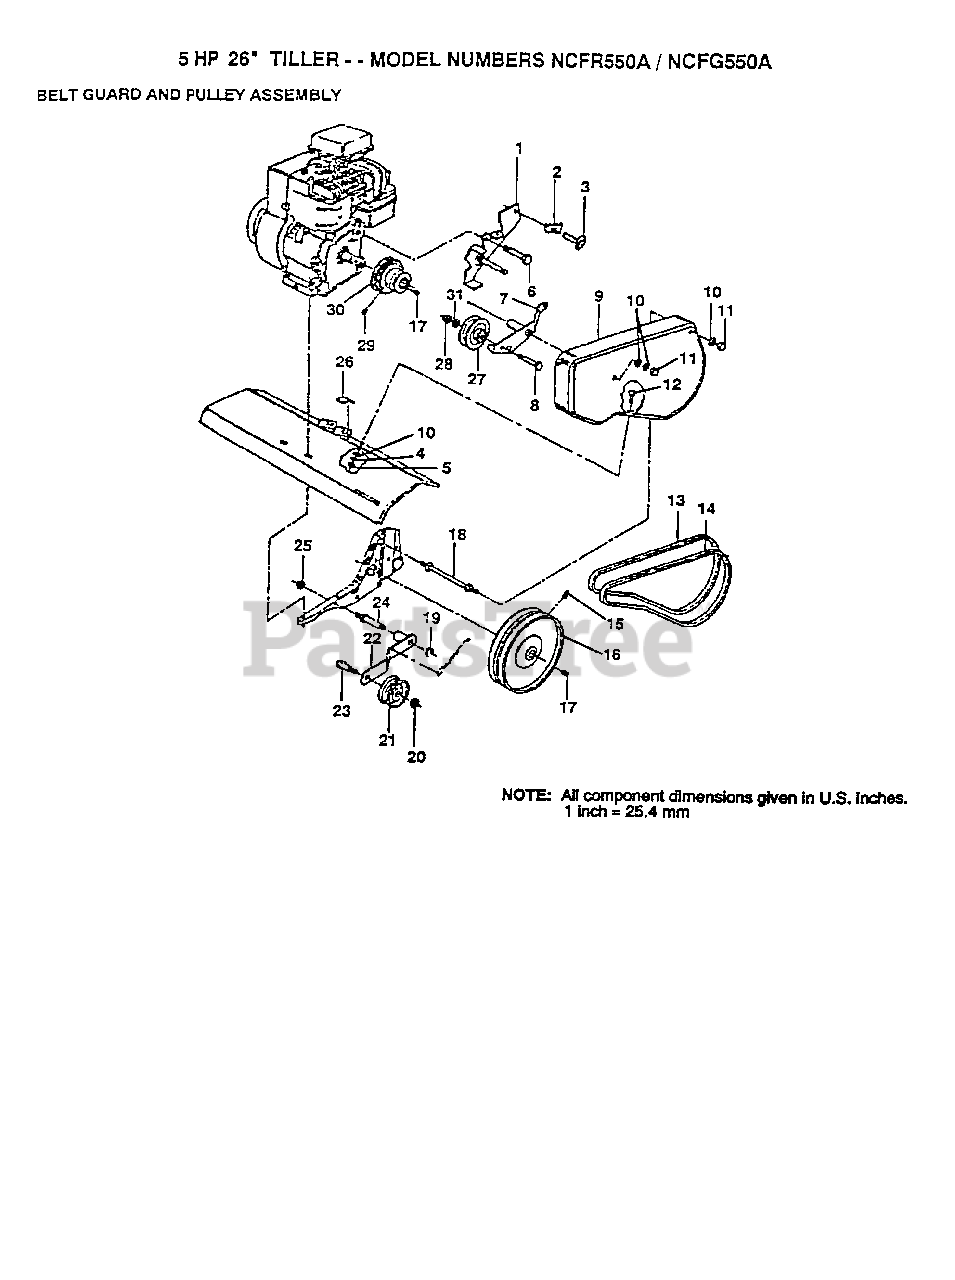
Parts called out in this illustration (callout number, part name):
2	CONDIUT CLIP T
4	LOCKWASHER
7	REV IDLER ARM TI
10	WASHER
11	NUT-CAP TI
12	BOLT T
15	SET SCREW
17	KEY T
18	BOLT TI
19	KLIP RING TI
20	NUT
22	IDLER ARM TI
24	SHAFT IDLER TI
25	JAM NUT TI
26	PAD IDLER TI
27	PULLEY W/SPACER
28	NUT.HEX.3/8-16UNC
29	SET SCREW
30	ENGINE PULLEY TI
31	WASHER
